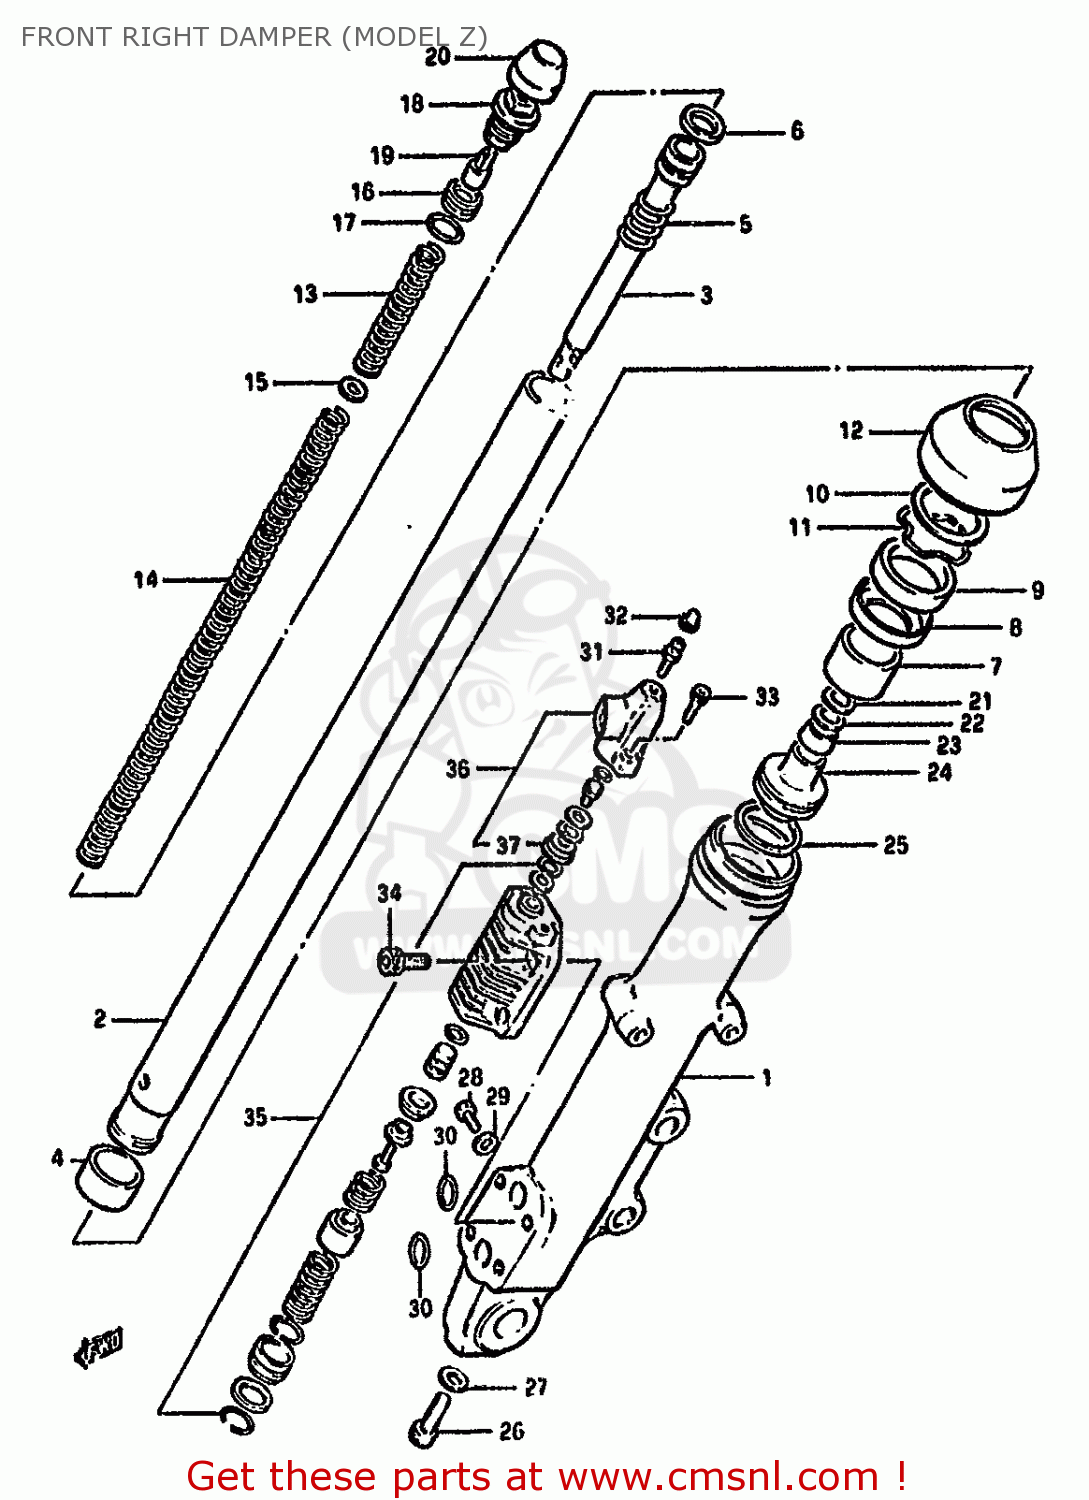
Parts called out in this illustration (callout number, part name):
1	OUTER TUBE RH
2	INNER TUBE
3	CYLINDER
4	PISTON
5	SPRING,FORK REBOUND
6	RING
7	BUSH,GUIDE
8	SPACER,SEAL
9	OIL SEAL,FRONT FORK
10	RING,FR FORK
11	CIRCLIP,FORK OIL SEAL
12	BOOT
13	SPRING (A)
14	SPRING (B)
15	WASHER,SPRING
16	SEAT, SPRING
17	O-RING
18	BOLT
19	ADJUSTER,SPRING
20	CAP
21	VALVE
22	SPRING,VALVE
23	VALVE,OIL LOCK PIEACE
24	PIECE,FRONT FORK OIL LOCK
25	PISTON RING,FRONT FORK
26	BOLT(8X27)
27	GASKET (NAS)
28	BOLT
29	GASKET,DRAIN,PLUG (NAS)
30	O RING,FR FORK
31	BREATHER
32	CAP
33	BOLT
34	BOLT
35	MODULATOR VALVE SET,FRONT
36	MODULATOR VALVE SET,FRONT
37	SEPARATOR,FRONT FORK MODULATOR
